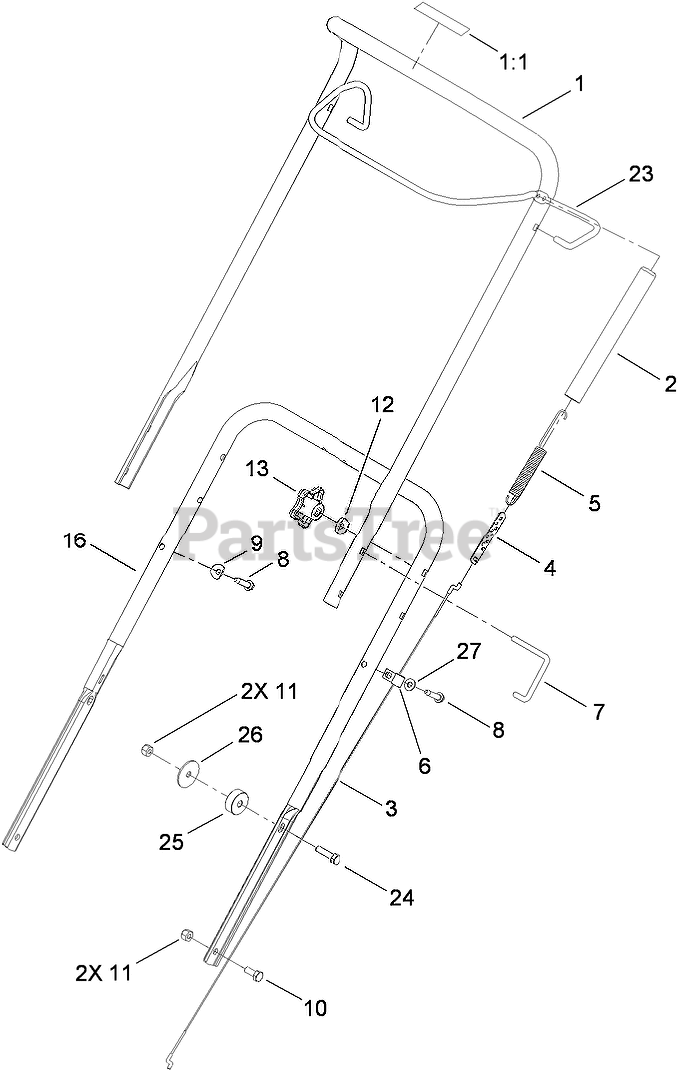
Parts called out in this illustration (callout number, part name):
1	UPPER HANDLE ASM
1:1	DECAL-DRIVE, ROTOR
2	COVER-SPRING
3	CABLE-CLUTCH
4	ADJUSTER-CABLE, CLUTCH
5	SPRING-EXTENSION
6	CLAMP
7	LOCK-HANDLE
8	SCREW-HWH
9	WASHER
10	SCREW-HH
11	NUT-LOCK, NI
12	WASHER
13	KNOB-HANDLE
16	HANDLE-LOWER
23	BAIL-CONTROL
24	SCREW-HH
25	SPACER
26	WASHER-FLAT
27	WASHER-FLAT
